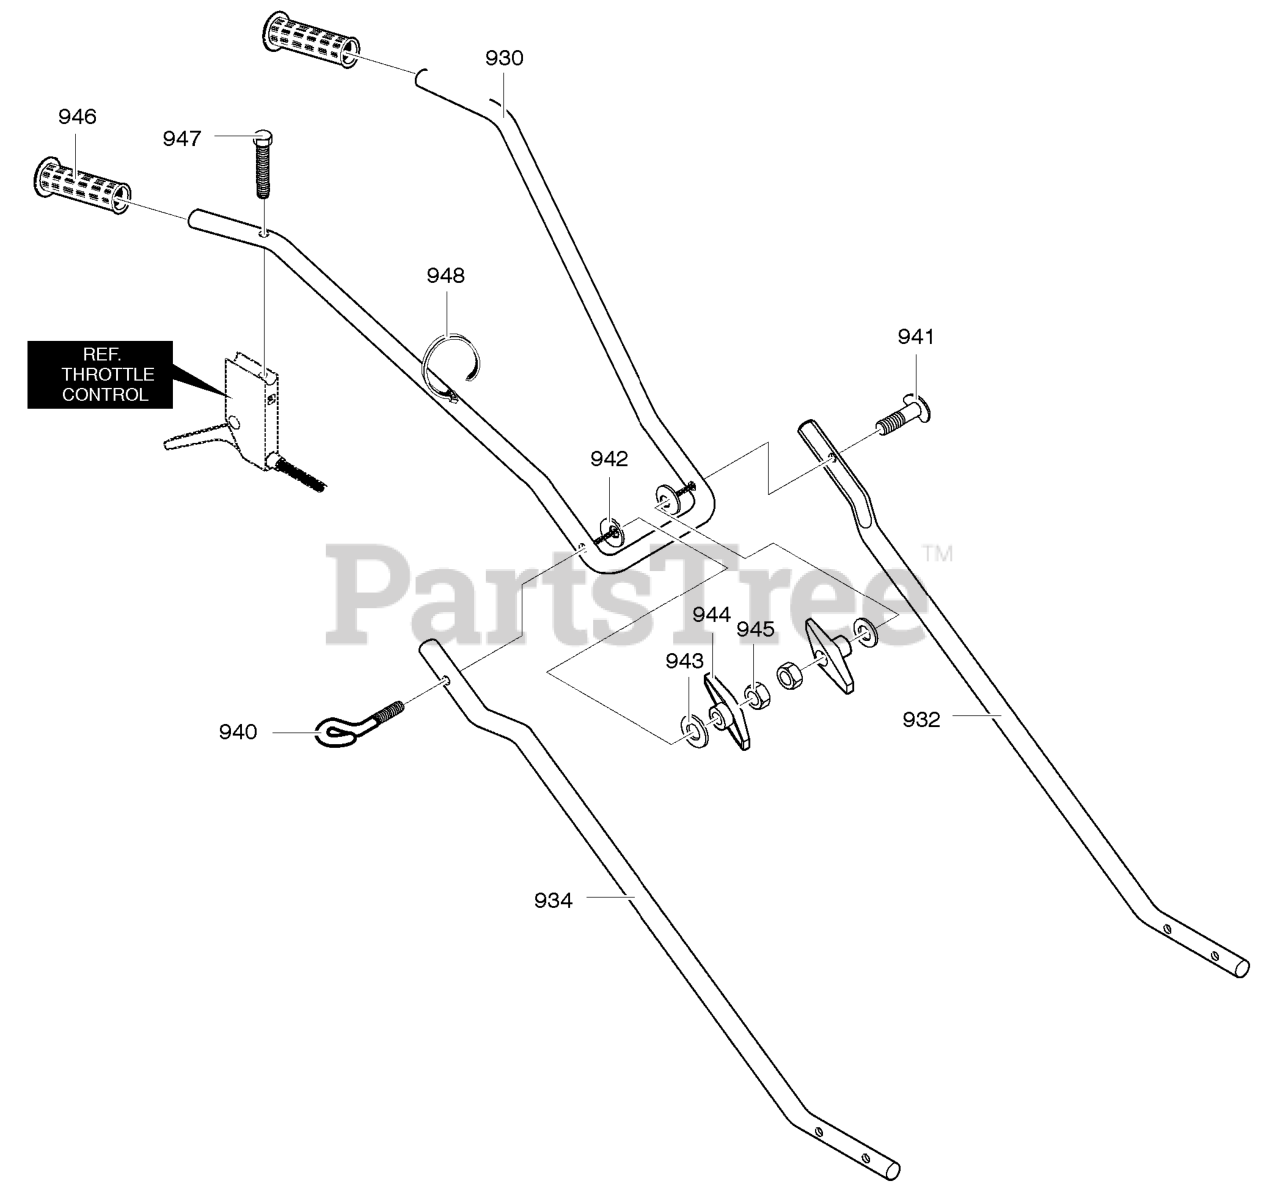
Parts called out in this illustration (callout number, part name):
930	Upper Handle
932	Lower Handle LH
934	Lower Handle RH
940	Guide, Rope
941	Bolt 5/16-18x1.63
942	Formed Washer
943	Flat washer
944	T Knob
945	Nut, 5/16-18
946	Hand Grip
948	Tie, Cable
